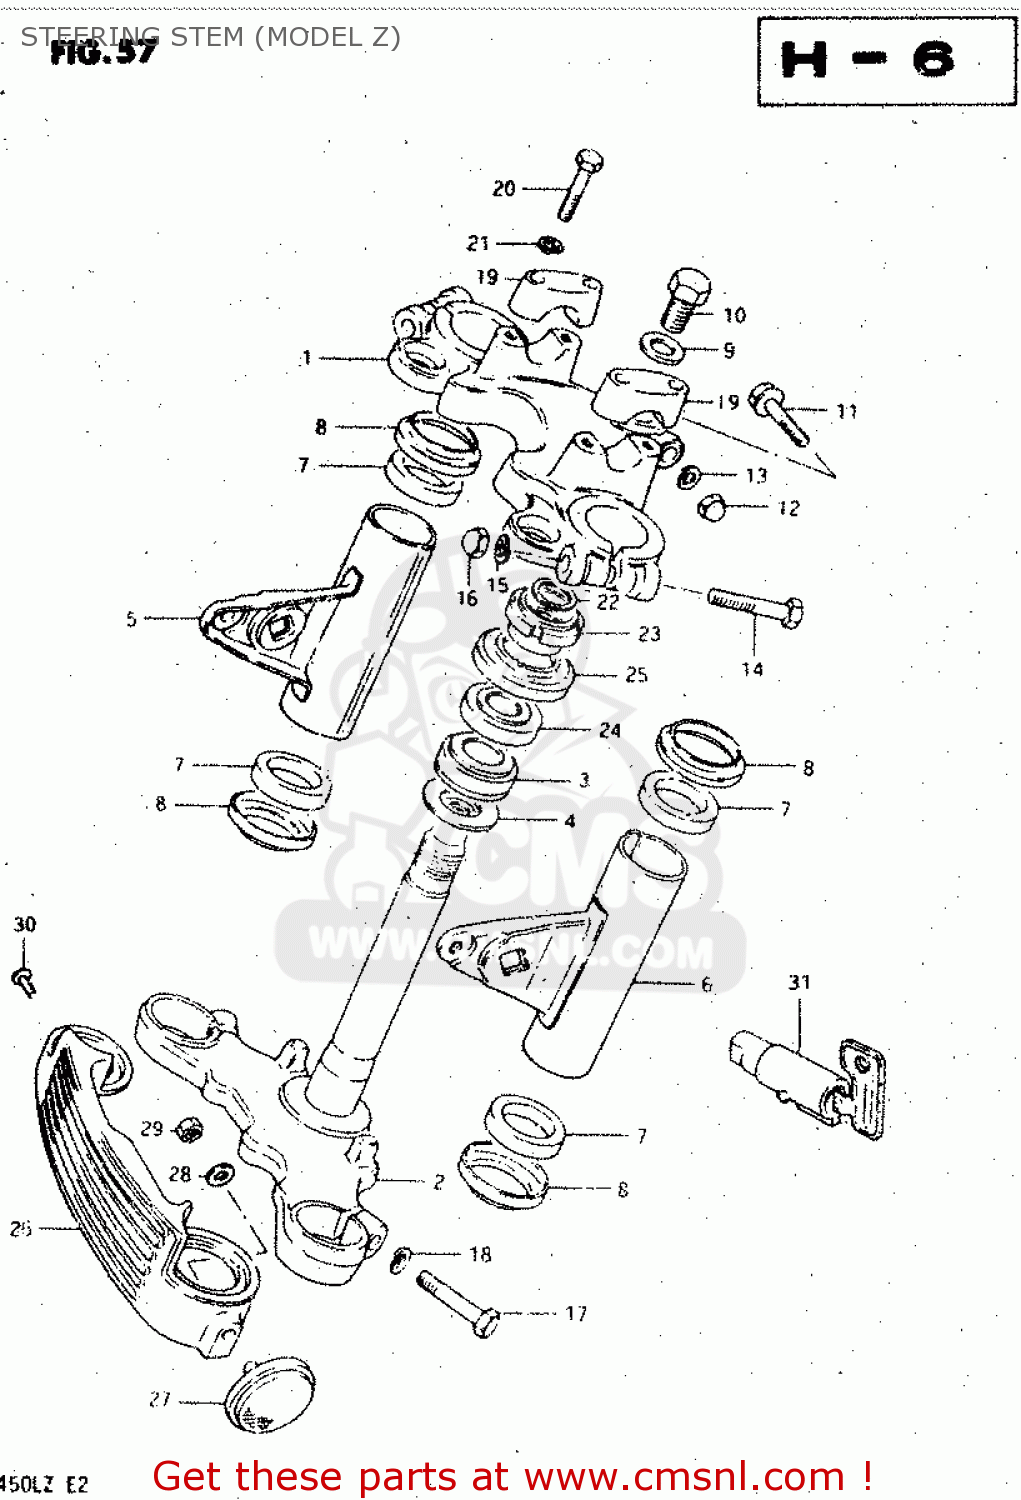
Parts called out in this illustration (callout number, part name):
1	HEAD,STEERING STEM
2	STEM,STEERING
3	BEARING
4	WASHER,THRUST
5	BRACKET,HEADLAMP,RIGHT
6	BRACKET,HEADLAMP,LEFT
7	CUSHION,HEADLAMP BRACKET
8	CAP,HEADLAMP BRACKET
9	WASHER
10	BOLT(12X20)
11	BOLT
12	NUT,M8X1.25X12
13	LOCK WASHER
14	BOLT 10X55
15	LOCK WASHER
16	NUT
17	BOLT 10X40
18	LOCK WASHER
19	HOLDER,HANDLE UPR
20	BOLT
21	LOCK WASHER
22	WASHER(18.5X24X1)
23	NUT,STEERING STEM
24	TAPER,ROLLER BEARING
25	DUST SEAL,STEERING UPR
26	COVER,FRONT FORK
27	REFLEX REFLECTOR,RR
28	WASHER
29	NUT
30	SCREW
31	LOCK ASSEMBLY,STEERING (NEI
